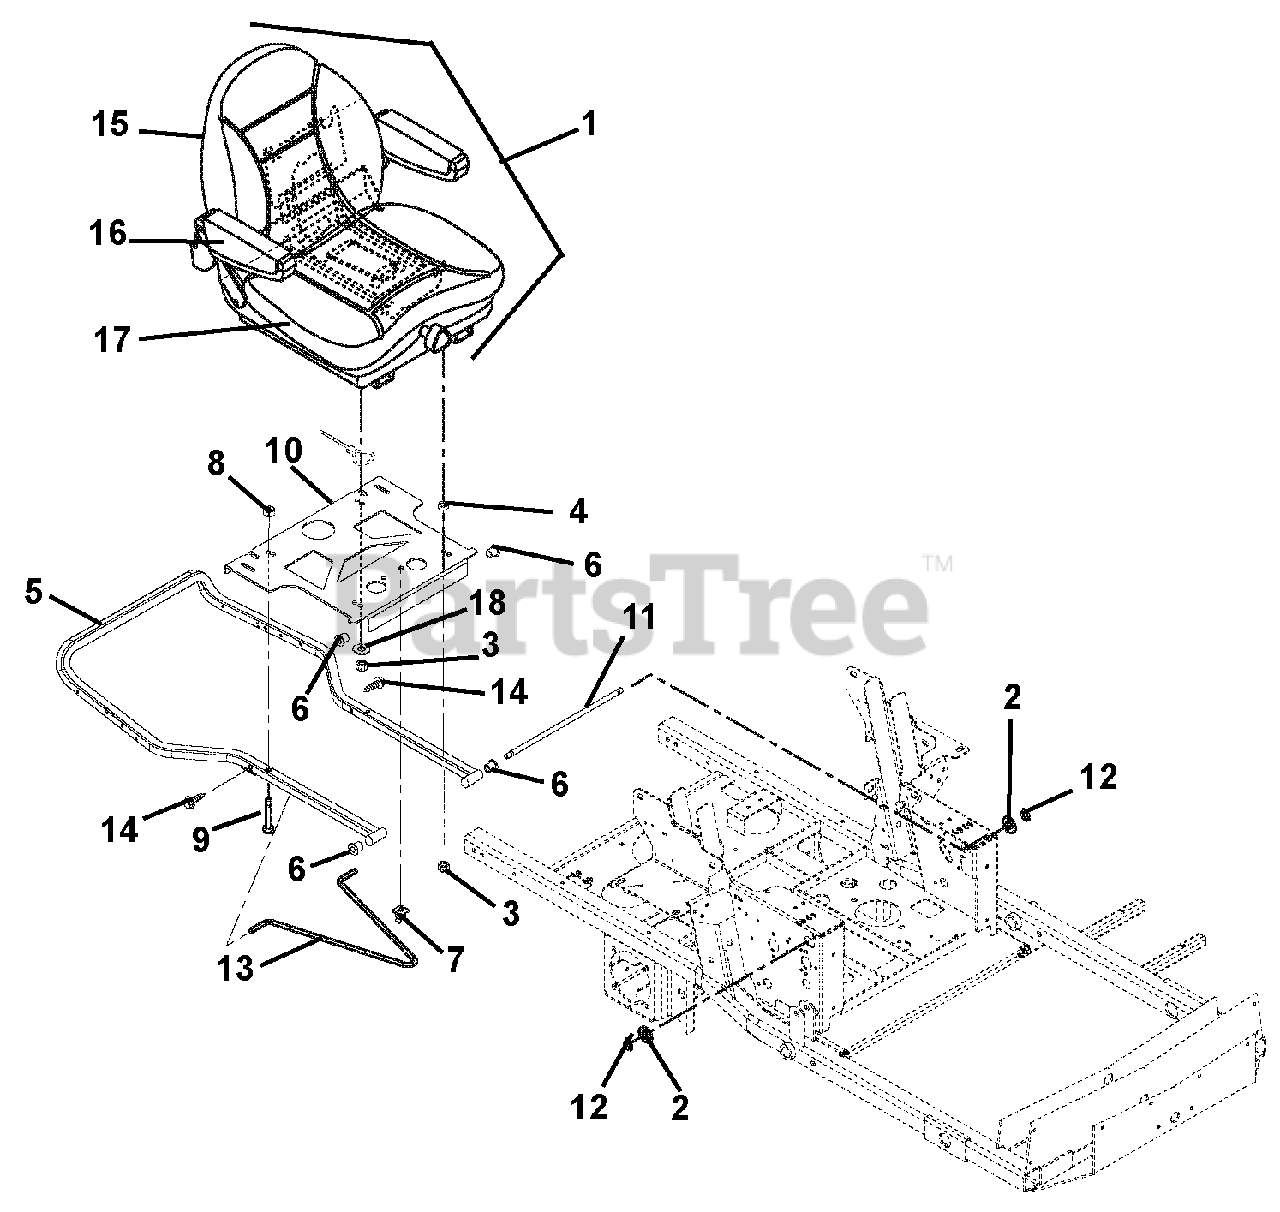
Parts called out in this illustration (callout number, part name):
1	Seat, Suspension
2	Washer, Flat Steel .531 x 1.06 x .095
3	Nut, Locking Top Flange .31-18
4	Bushing, Sleeve .377 x .624 x .235
5	Weldment, Hood Frame
6	Bushing-Flange .515 x .750 x .745 x 1.00
8	Nut, Locking Top Flange .38-16
9	Bolt, Rib Neck .38-16 x 1.50
10	Weldment, Seat Pivot Plate
11	Rod, Seat Frame Pivot
12	Ring, Retaining External .500 x .050
13	Rod, Prop
14	Screw, Tapping .25-20 x .50 Hex Washer Head
15	Kit, Back Cushion
17	Kit, Seat Cushion
18	Washer, Flat Steel .328 x 1.00 x .094
